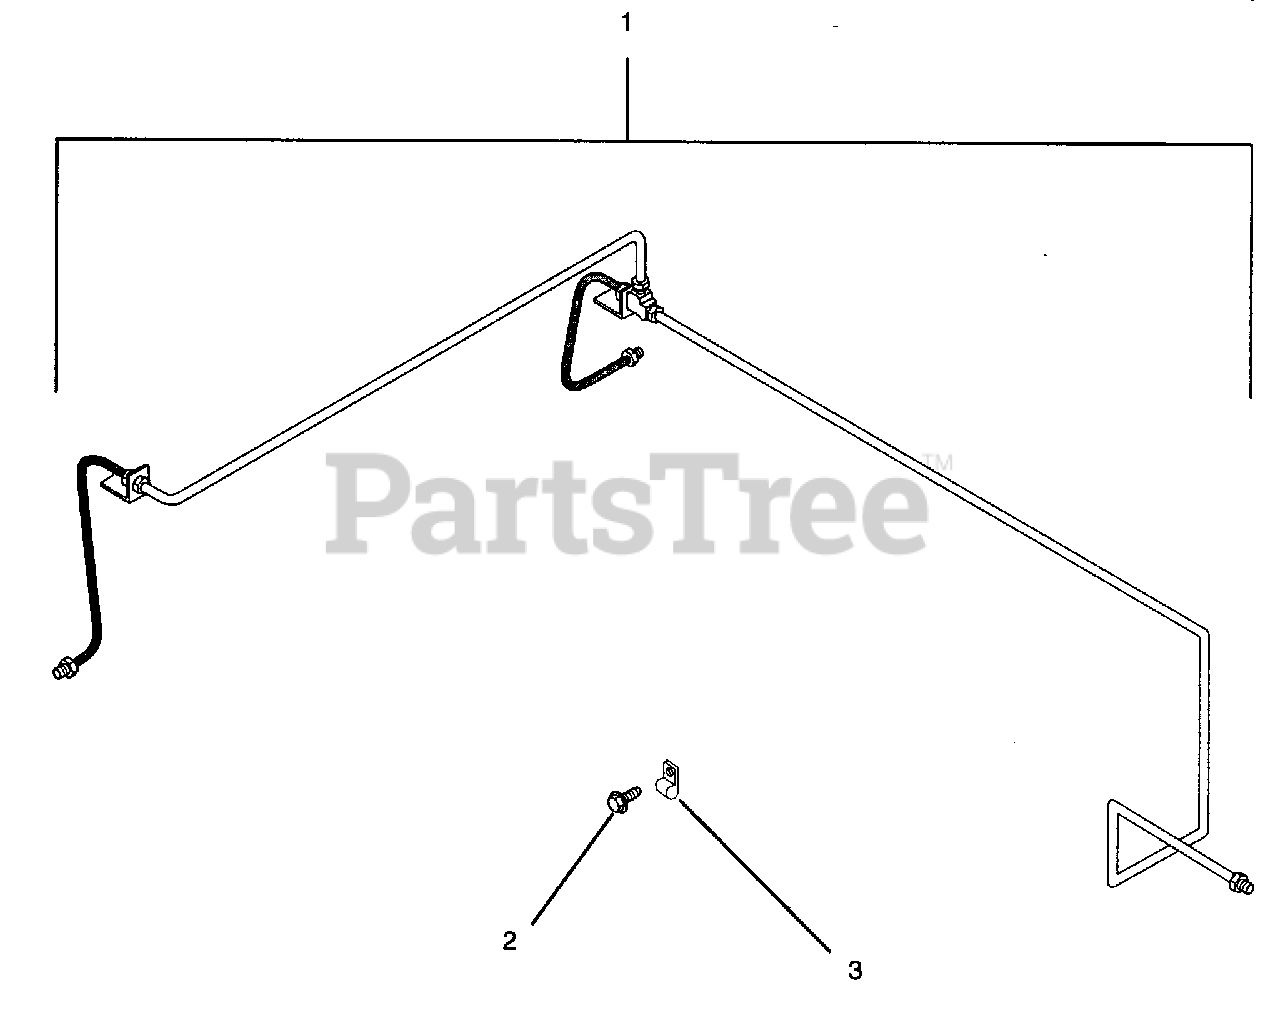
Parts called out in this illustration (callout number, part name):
1	Brake Line Kit
2	Screw-Tapping 10-16 x .75 Hex Washer Head
3	Clamp-Tubing
